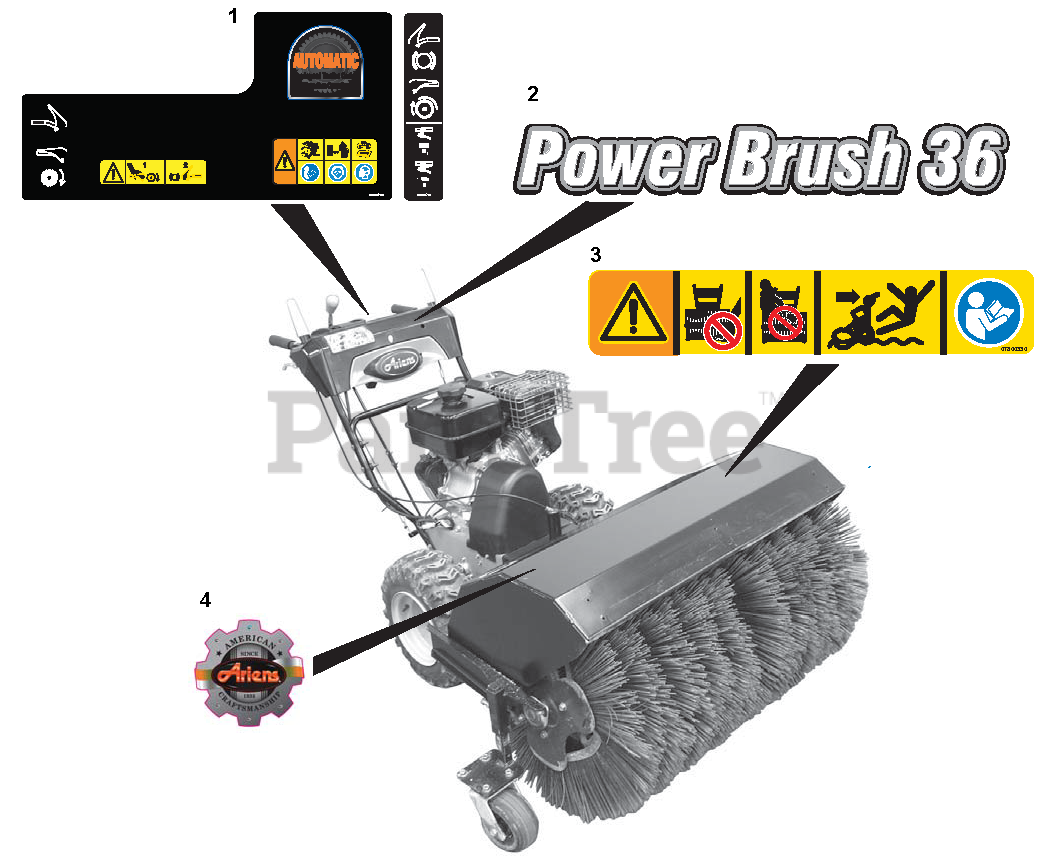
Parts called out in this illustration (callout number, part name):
1	DECAL, CONTROL, LARGE BRUSH
2	DECAL, FRONT-ARIENS PB36
3	DECAL, DANGER -POWER BRUSH-CE
4	Decal, Ariens Heritage - Large
